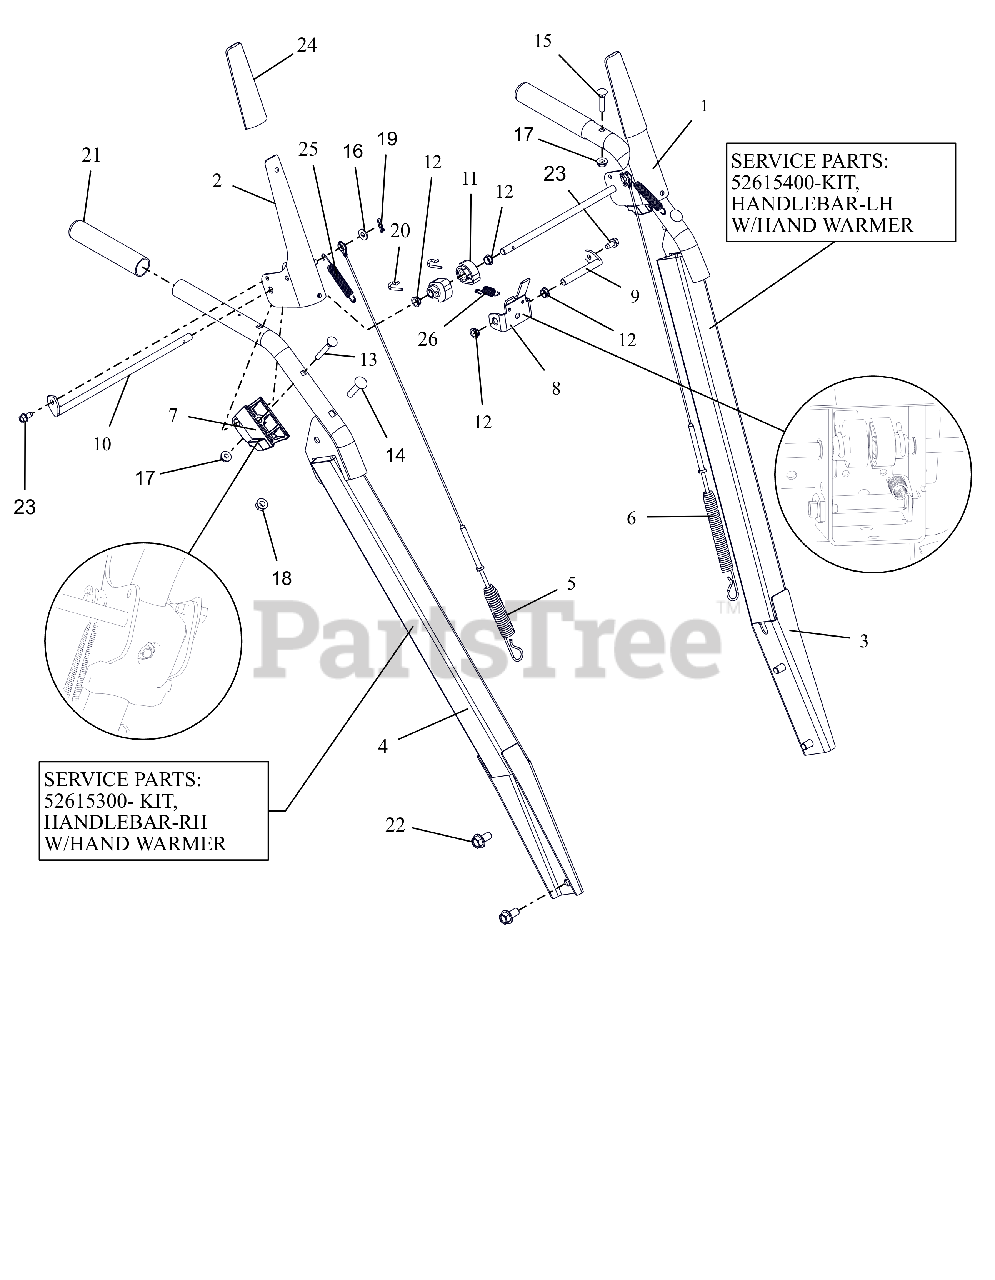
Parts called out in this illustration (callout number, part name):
1	LEVER, CLUTCH-LH
2	LEVER, CLUTCH-RH
3	HANDLEBAR, HEAVYDUTY-PRO LH
3	KIT, HANDLEBAR-LH W/WARM GRIP
4	HANDLEBAR, HEAVYDUTY-PRO-RH
4	KIT, HANDLEBAR-RH W/WARM GRIP
5	CABLE, AUGER (DELUXE & PRO)
6	CABLE, UPPER TRACTION
7	BLOCK, CLUTCH PADDLE
8	BRACKET, INTERLOCK ARM
9	ROD, PIVOT - INTERLOCK
10	ROD, PADDLE MOUNT - PRO
11	CAM, INTERLOCK
12	BUSHING, POLYLINER-.38 SNAPIN
13	BLT-RDHDXLSQNK .25-20X2.0 G5YZ
14	BLT,RHSN .31-18X1.50 G5 ZCC
15	BLT-RDHDXLSQNK.25-20X1.25 G5ZC
16	WSHR,FLT .281X.625X.065 ZCC
17	NUT-LK-CTR-FLG .25-20 ZC120
18	NUT-LK-TOP-FLG .312-18 GF ZCC
19	PIN, HAIR #178 .06X.77 ZCC
20	PIN, SPRING CLIP
21	GRIP,HANDLE-GRAY
22	BLT-SERHFWH .38-16X.75 YWZC
23	SCR-TAP .25-20X.50 HWH ZCC
24	SLEEVE, CLUTCH PADDLE-GRAY
25	SPRING, EXTENSION
26	SPRING-EXT .047X.438X1.45
